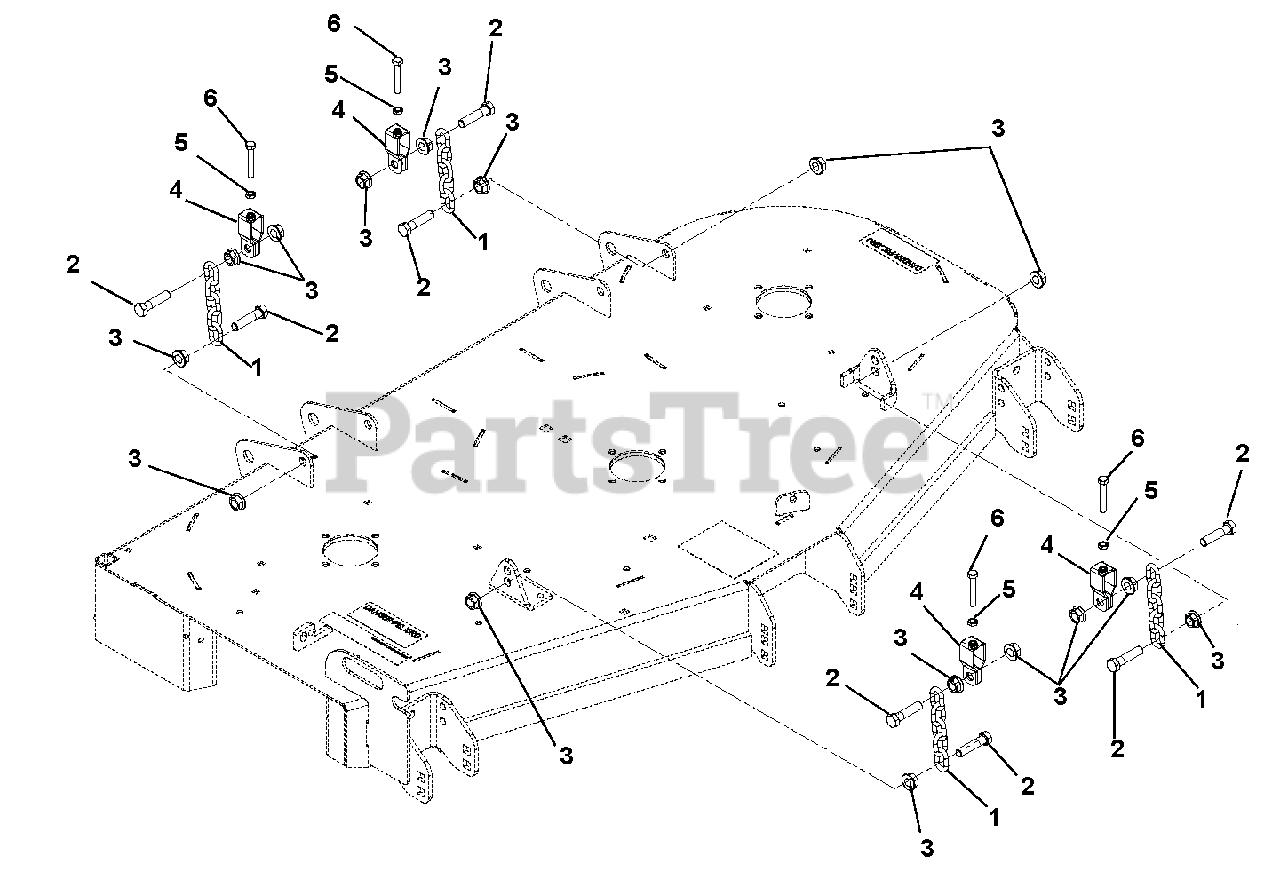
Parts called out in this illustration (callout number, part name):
1	CHAIN, LINK
2	BLT, HEX M12-1.75X50 CLS8.8 YZ
3	NUT-SPNLK-FLG M12-1.75 YZ
4	BRKT, DECK LEVELING
5	NUT- JAM .312-18 YWZC
6	BLT-HEX .312-18X2.00 FTH GR5YZ
